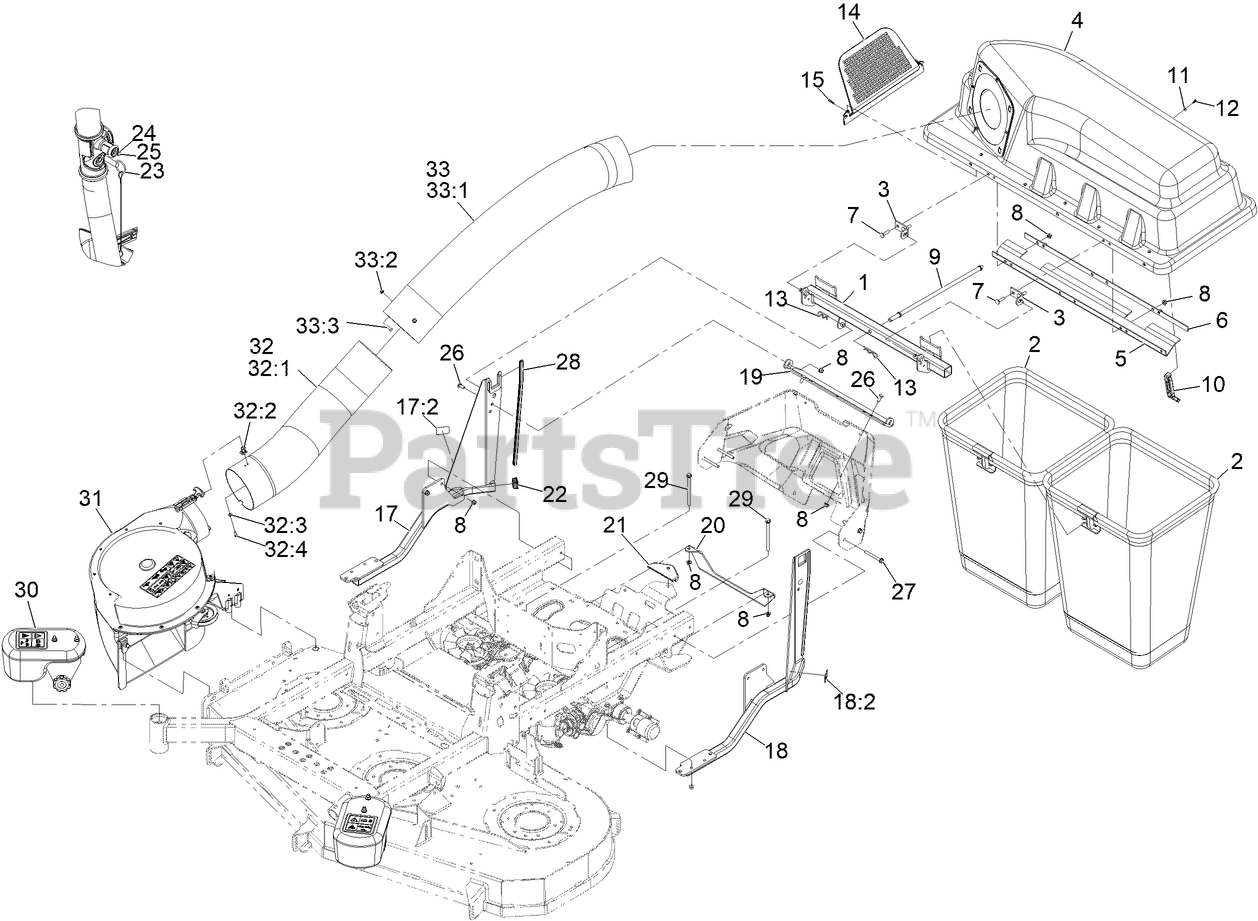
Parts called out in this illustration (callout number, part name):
1	WELD, HOOD PIVOT
2	BAG AND FRAME ASM
3	BRACKET-PIVOT, HOPPER
4	BAGGER HOOD ASM
6	PLATE-BACKING
7	Bolt-Carriage 5/16-18 X 1 1/4
8	NUT-HF, NI
9	ROD-HOLD DOWN, HOOD
10	LATCH-RUBBER
11	WASHER-FLAT
12	SCREW-PLASTITE
13	PIN-HAIR
14	SCREEN-BAGGER
17	ASM, SUPPORT W/ DECAL, RT
17:2	DECAL-WARNING
18	ASM, SUPPORT W/ DECAL, LT
18:2	DECAL-WARNING
19	Angle - Support, Bagger
20	SUPPORT-TRANSMISSION
21	COVER-HITCH
23	HITCH PIN ASM
24	WASHER-FLAT
26	SCREW-CARR
27	SCREW-HHF
28	Strip-Trim
29	SCREW HHF
30	CASTER WEIGHT KIT
31	ASM, POWERED BLOWER
32	LOWER TUBE ASM
32:1	TUBE-LOWER
32:2	LATCH-KEEPER
32:3	WASHER-FLAT
32:4	SCREW-PPH
33	UPPER TUBE ASM
33:1	TUBE-UPPER
